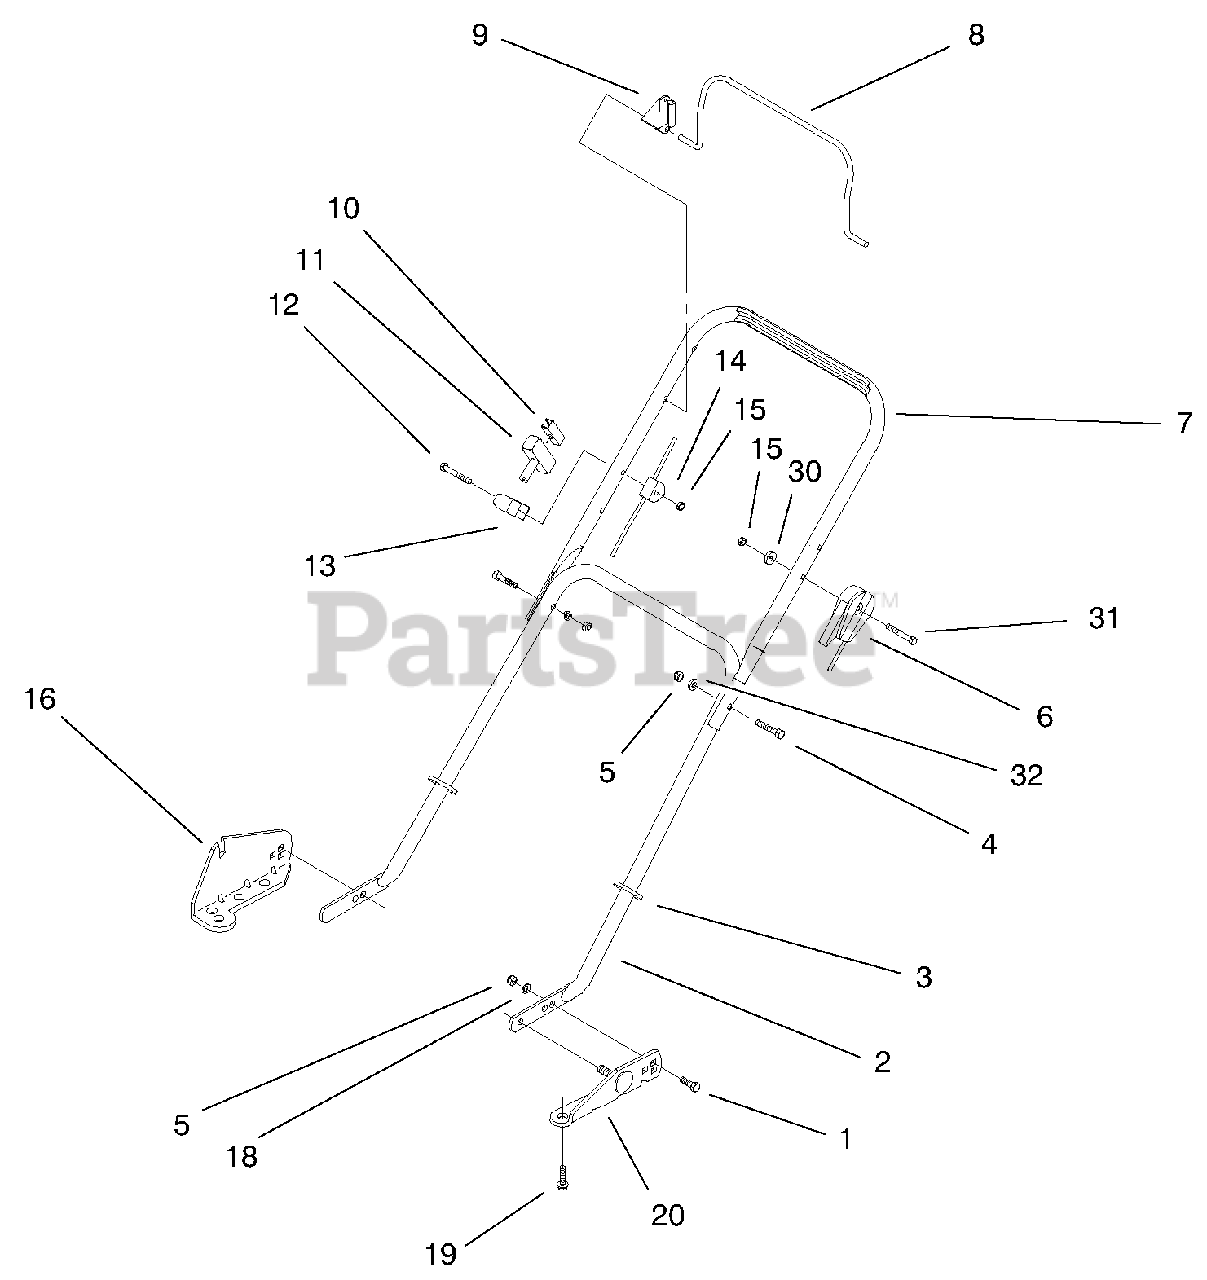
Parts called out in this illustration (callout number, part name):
1	Bolt-CARR
2	Handle Section-Lower
3	Tie Strap
4	Screw-HH
5	Nut-Lock
6	Cable-Throttle
7	Handle Section-Upper
8	Bail-Flywheel Brake
9	Stop-Pivot
10	Clip-Rope
11	Handle-Starter
12	Screw-HH
13	Guide-Rope
14	Cable-Flywheel Brake
15	Nut-Lock
16	ASM-Bracket & Pin
18	Washer-Lock
20	ASM-Bracket & Pin
30	Washer
31	Screw-HH
